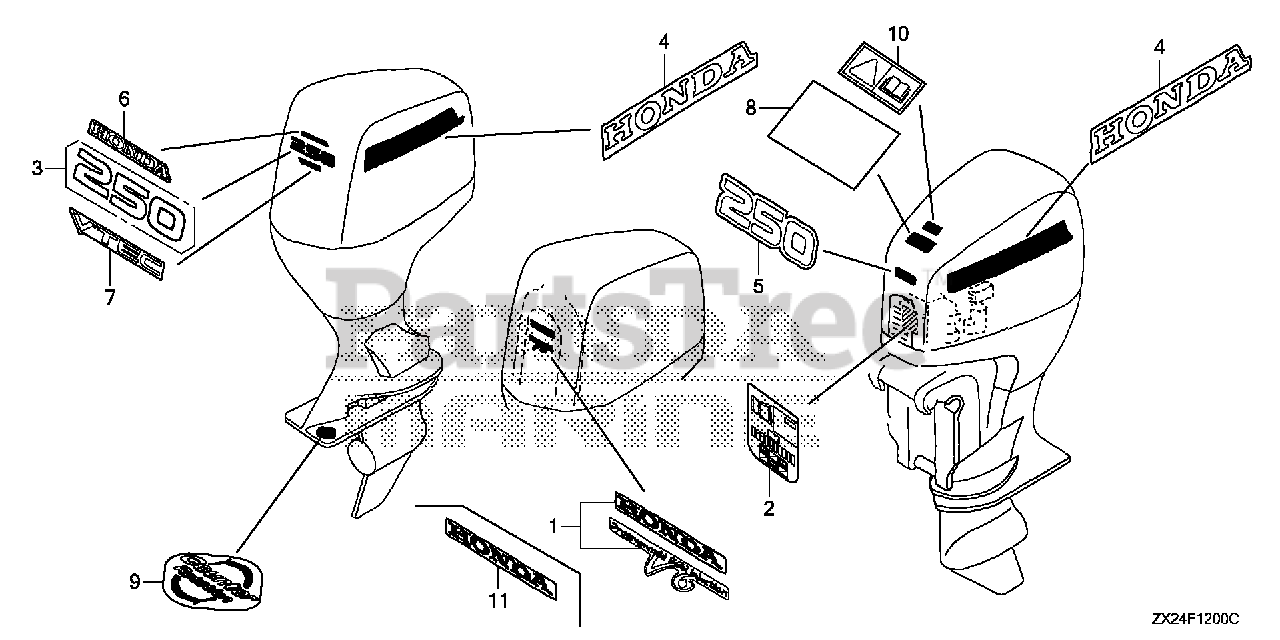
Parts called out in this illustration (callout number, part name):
1	MARK, EMBLEM
2	LABEL, FUSE & OIL CAUTION
3	MARK, RR. (250)
4	MARK, SIDE STRIPE (HONDA)
5	MARK, FR. EMBLEM (250)
6	MARK, HONDA
7	MARK (VTEC)
8	LABEL, OPERATOR CAUTION (ENGLISH)
8	LABEL, WARNING OPERATOR
9	MARK, COUNTER ROTATION
11	EMBLEM (13 (HONDA)
